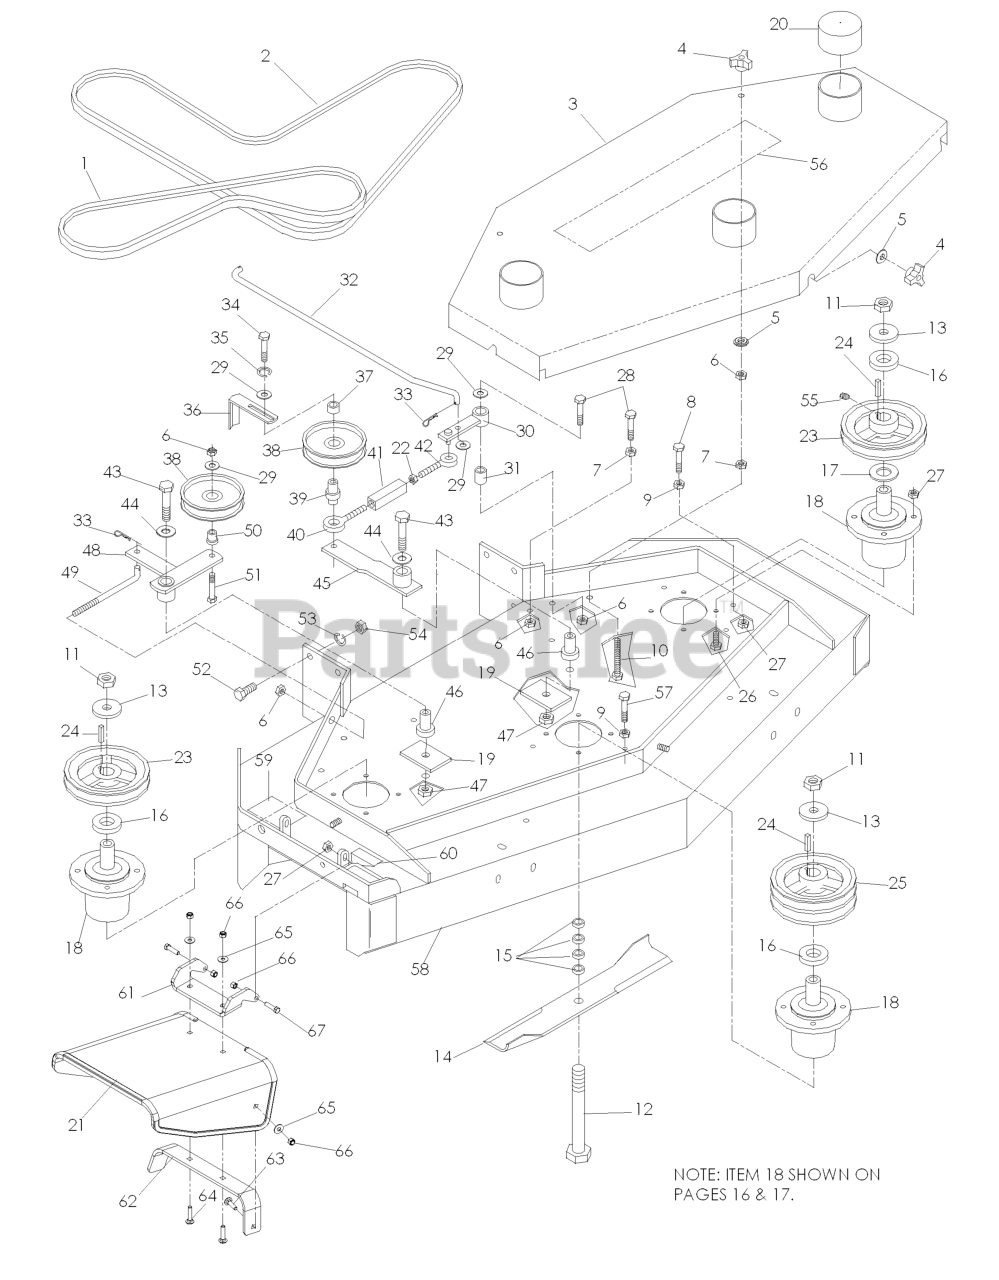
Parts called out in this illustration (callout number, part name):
1	BELT, AUX BLADE
2	BELT - ENG/DECK 48
3	BELT SHIELD 48"
4	KNOB, THREE PRONG
5	WASHER, 3/8 SEALING
6	NUT 3/8C CENTERBLOCK
7	NUT 3/8C WHIZ
8	HCS 5/16 X 3
9	NUT 5/16C WHIZ
10	TAPBOLT 3/8C X 4 1/2
11	NUT 5/8F HEX
12	HCS 5/8F X 8 1/2
13	SPINDLE WASHER
14	BLADE OEM 16 1/4"
15	BLADE SPACERS
17	MACHINERY BUSHING 10 GA.
18	HOUSING ASSEMBLY
21	CHUTE, RUBBER DISCHARGE WB
22	NUT 5/16C HEX
23	PULLEY W/SETSCREWS
24	KEY 1/4 SQ X 1 1/8
25	PULLEY, DOUBLE W/SETS
26	HCS 5/16C X 1
27	NUT 5/16C CENTERLOCK
28	HCS 3/8C X 2 1/4
29	WASHER 3/8 FLAT
30	ENGAGEMENT ARM
31	BUSHING, SLEEVE
32	BLADE ROD 48"
33	HAIRPIN #2
34	HCS 3/8C X 2 1/2
35	SLW 3/8 STD
38	IDLER PULLEY
39	EYEBOLT PIVOT
40	EYEBOLT, LH
41	TURNBUCKLE
42	EYEBOLT, RH
43	HCS 1/2C X 2 3/4
44	WASHER 1/2 FLAT
45	ARM WELDMENT
46	IDLER SPINDLE
47	NUT 1/2-13 HEX NYLOC ZD
48	IDLER ARM, AUX.
49	TENSION ROD
50	BUSHING, IDLER FLANGE
51	HCS 3/8-16 X 1 3/4 GR5
52	HCS 7/16C X 1 1/2
53	WASHER 7/16 LOCK
54	NUT 7/16C HEX
55	SET SCREW 5/16 NYLOC
56	DECAL, HUSQVARNA 17.5"
57	HCS 5/16C X 4
58	DECK W/DECALS 48"
59	DECAL, EURO SEVERING
60	DECAL, CPSC
61	PIVOT BRACKET - CHUTE
62	BRKT, REINF-CHUTE WB
63	BOLT, CARRIAGE 5/16X1-1/4
64	RHSNB 5/16-18 X 1-1/2 GR 5 ZD
65	WASHER 5/16 FLAT
66	NUT 5/16 NYLOC
67	HCS 5/16C X 1 1/4
